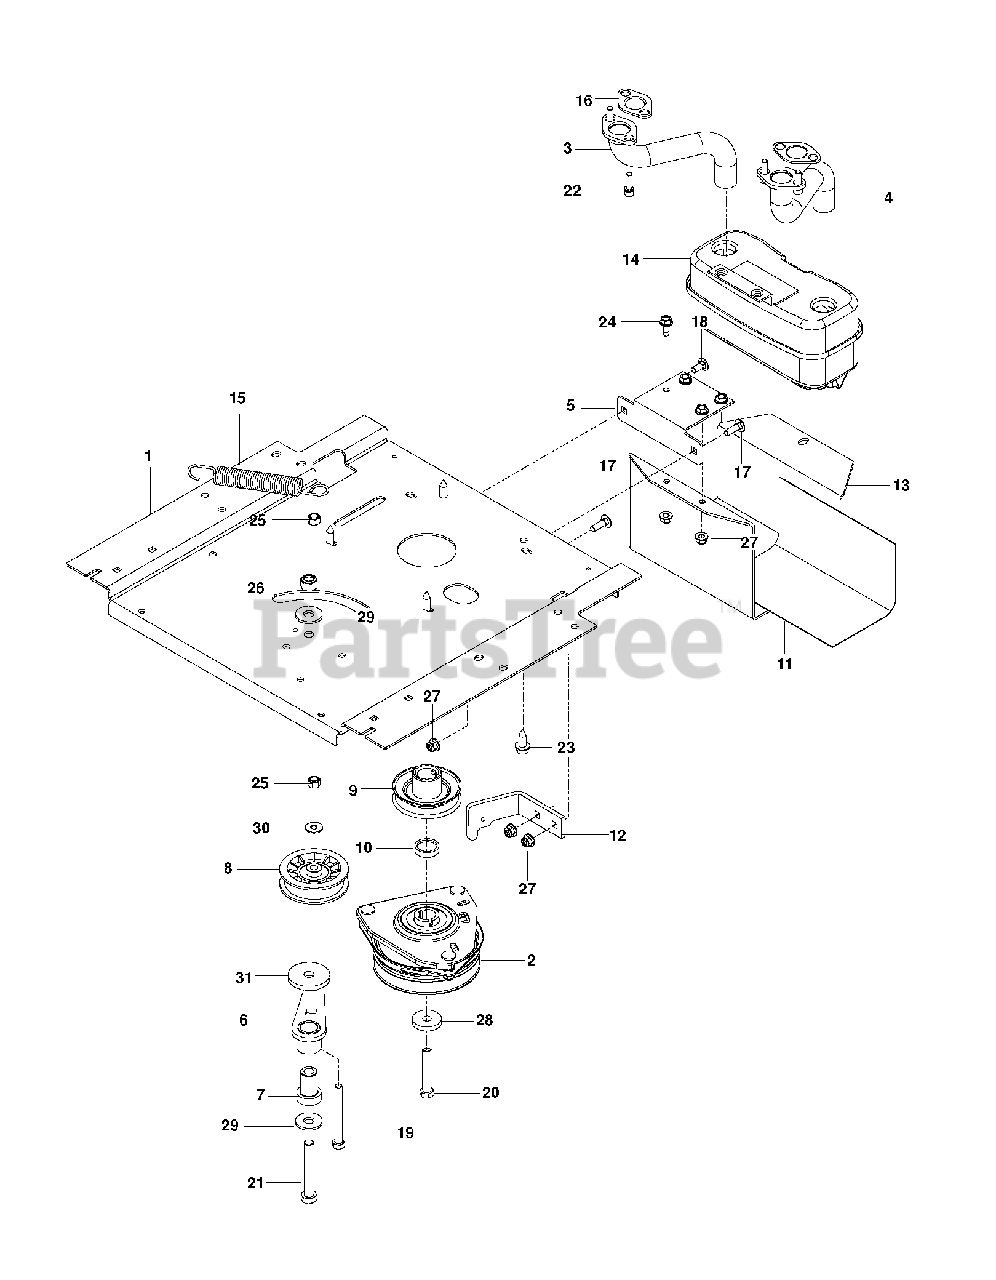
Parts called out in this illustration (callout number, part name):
1	PLATE.ENGINE.PNT.23".RZ.EDIP
2	CLUTCH.ELECTRIC.LT.48"*
3	EXHAUST.TUBE.LH.BS/TWIN
4	EXHAUST.TUBE.RH.B&S.TWIN.INTEK
5	BRACKET MUFFLER MS431BLK
6	ARM IDLER
7	IDLER SPINDLE
8	PULLEY, IDLER RAKE & ZTR
9	RP PULLEY, ENGINE
10	SPACER, HUB PULLEY
11	HEAT SHIELD
12	CLUTCH STOP OGR BLK
13	GUARD.MUFFLER.WO.TOW.HITCHX431
14	MUFFLER ASM TWIN
15	SPRING, DECK DRIVE
16	GASKET.MUFFLER
18	BOLT 5/16-18 X3/4 ZN/YEL GR 5
19	HCS 3/8-16X3-1/2 TAPBLT GR5 ZD
20	CLUTCH BOLT7/16-20X2.5 GR524HR
21	HCS 1/2-13 X 3-1/4 GD 5 ZD
22	SCREW.SOCKET.HEAD.5/16-18
23	SCREW 3/8-16X1
24	SCREW
25	NUT 3/8-16 NYLOC
26	NUT.LK.W/WSH.1/2.
27	5/16-18 NYLOC FLANGE NUT
29	WASHER.9/16 X 1 3/8 X 12 GA.
30	WASHER
31	HEAVY WASHER
